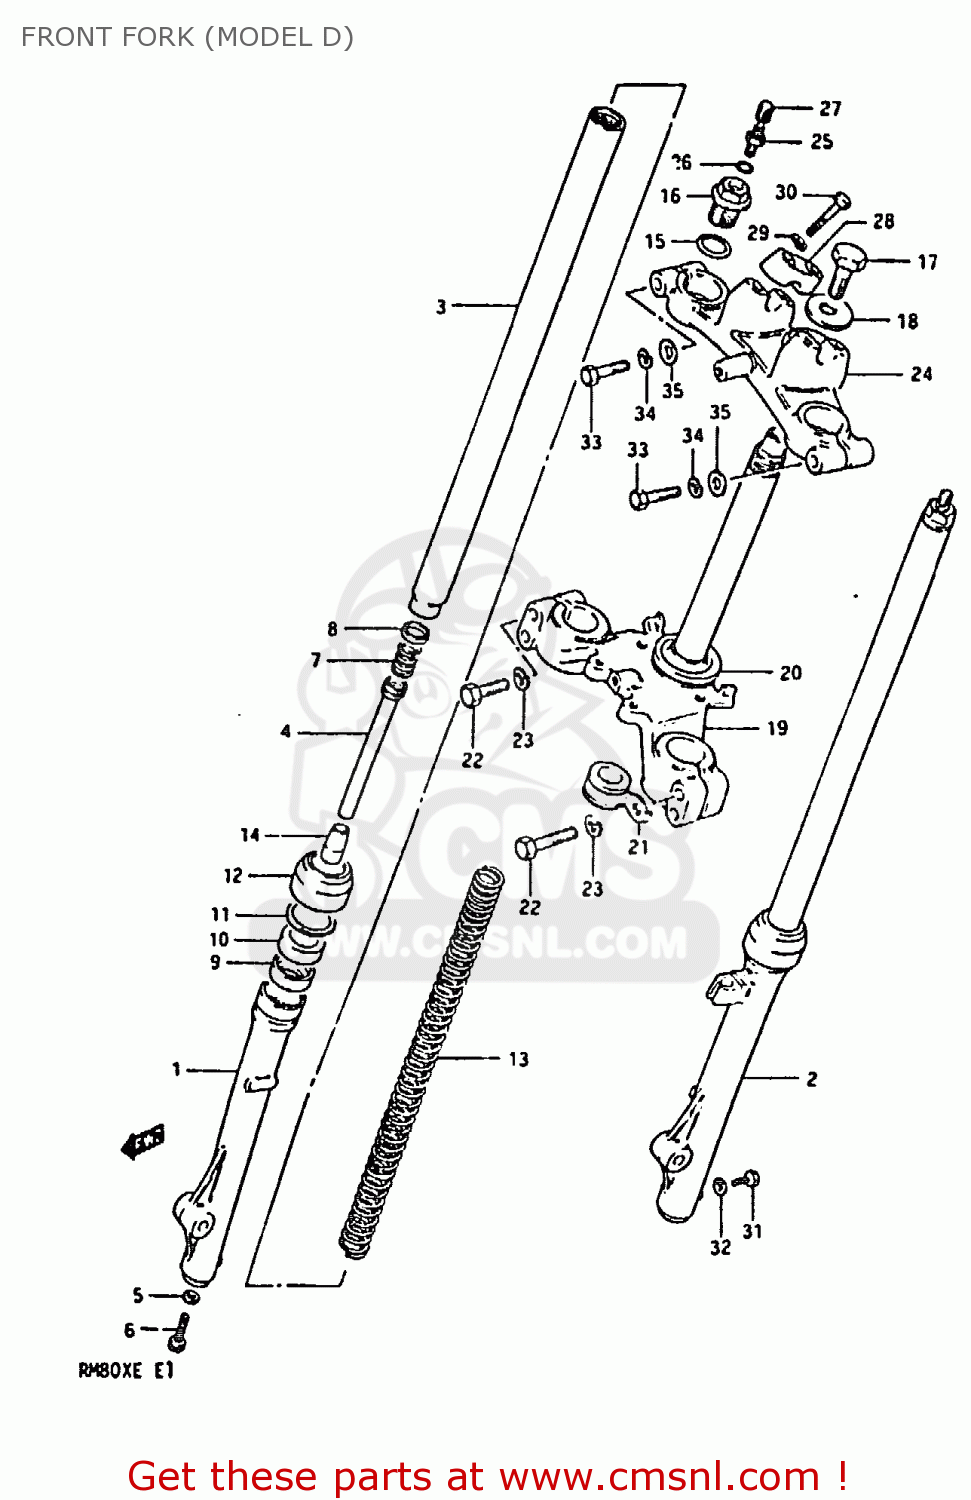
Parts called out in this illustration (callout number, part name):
1	TUBE,OUTER,RIGHT
2	TUBE,OUTER,LEFT
3	TUBE,INNER
4	CYLINDER,FRONT FORK
5	GASKET (NAS)
6	BOLT(8X27)
7	SPRING,REBOUND
8	RING,PISTON
9	SPACER,FORK OIL SEAL
10	SEAL,OIL
11	CIRCLIP,FORK OIL SEAL
12	SEAL,DUST
13	SPRING,FRONT FORK
14	PIECE,OIL LOCK
15	O RING
16	BOLT,FORK INNER TUBE
17	BOLT,STEERING STEM HEAD
18	WASHER
19	STEM,STEERING
20	RACE,STEERING OUTER LWR
21	GUIDE,CABLE
22	BOLT,FORK INNER TUBE F
23	LOCK WASHER
24	STEM HEAD,STEERING
25	VALVE,AIR
26	O-RING
27	CAP
28	HOLDER,HANDLEBAR
29	LOCK WASHER
30	BOLT
31	BOLT
32	GASKET,DRAIN,PLUG (NAS)
33	BOLT 8X40
34	LOCK WASHER
35	WASHER
